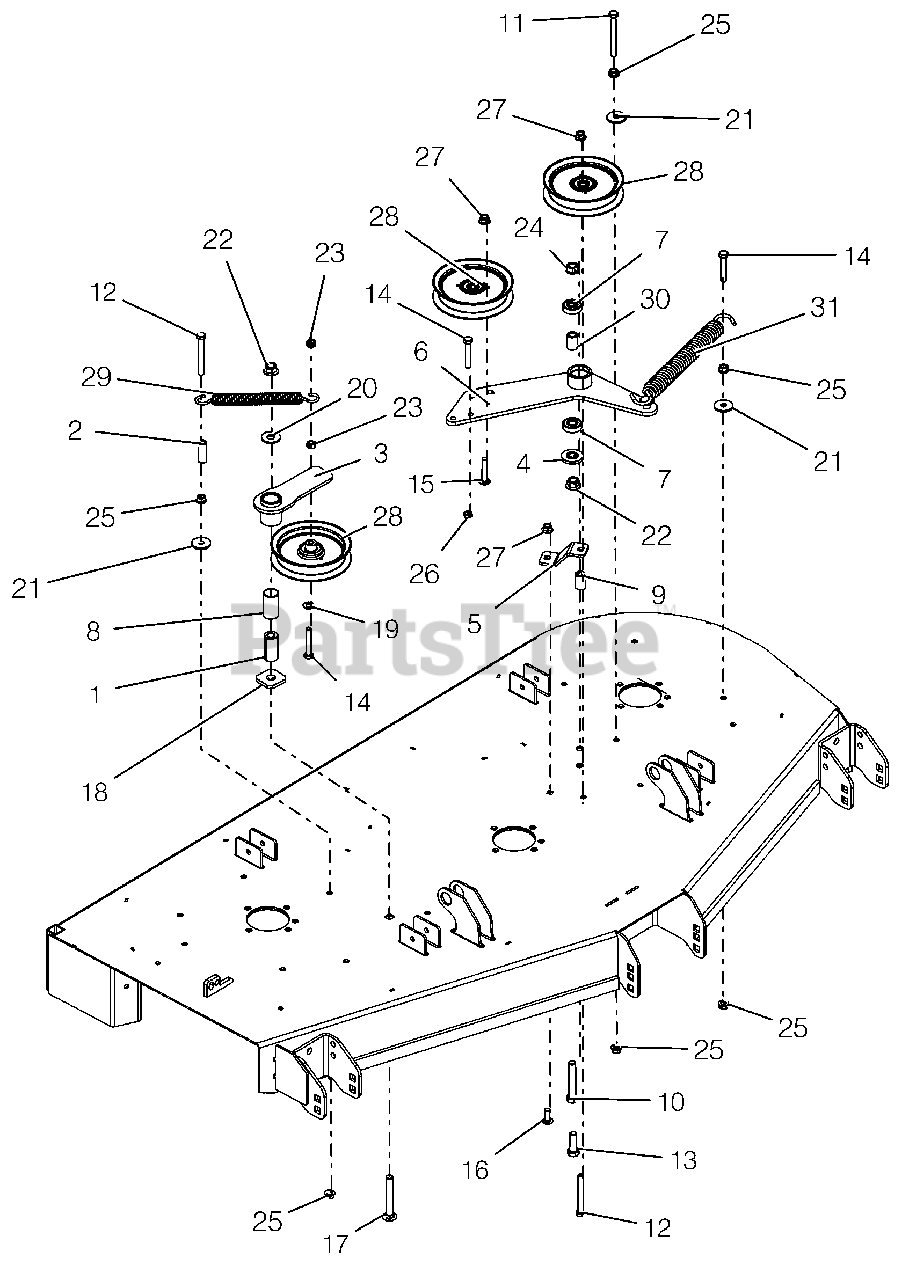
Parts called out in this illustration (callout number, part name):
1	BSHG, SPCR .502X.997X2.03 PM
2	SPACER, .375IDX.625ODX1.66 PM
3	WMT, IDLER ARM - BLACK
4	SPACER, IDLER ARM
5	PTO FIXED IDLER MTG BRKT -RED
6	DECK PTO IDLER ARM WLDMT - BLK
7	BRG-BALL .500X1.38X.437
8	BSHG, 1.00X1.125X1.937
9	BUSHING, SLV .380X.750X1.190
10	@BLT-HEX .50-13X3.00 GR5 YWZC
11	@BLT-HEX .38-16X3.50 GR5 YWZC
12	@BLT-HEX .38-16X3.25 GR5 YWZC
13	@BLT-HEX .50-13X1.50 GR5 YWZC
14	@BLT-HEX .38-16X2.25 GR5 YWZC
15	BLT-RDHDSQNK .38-16X2.00 SHTYW
16	@BLT-RDHDSHSQNK.38-16X1.0 G5YZ
17	@BLT-RDHDSQNK .50-13X3.50 G5YZ
18	WSHR-FLT .640X1.75X.250
19	@WSHR-FL-STL.406X.812X.065 YWZ
20	@WSHR-FL-STL.563X1.38X.109YWZC
21	WSHR-FL-STL .406X1.375X.135 YZ
22	@NUT-LK-NYL-FLG .50-13 YWZC
23	@NUT-LK-CTR .38-16 YWZC
24	NUT-LK-CTR-FLG .50-13 YWZC
25	@NUT-SPNLK-FLG .375-16 YWZC
26	NUT-HEX-JAM .375-16 YWZC
27	@NUT-LK-NYL-FLG .38-16 YWZC
28	IDLER, FLAT 5.00"
29	SPRING, EXTENSION
30	SPACER .510 X .75 X 1.1485
31	SPRING, EXTENSION
